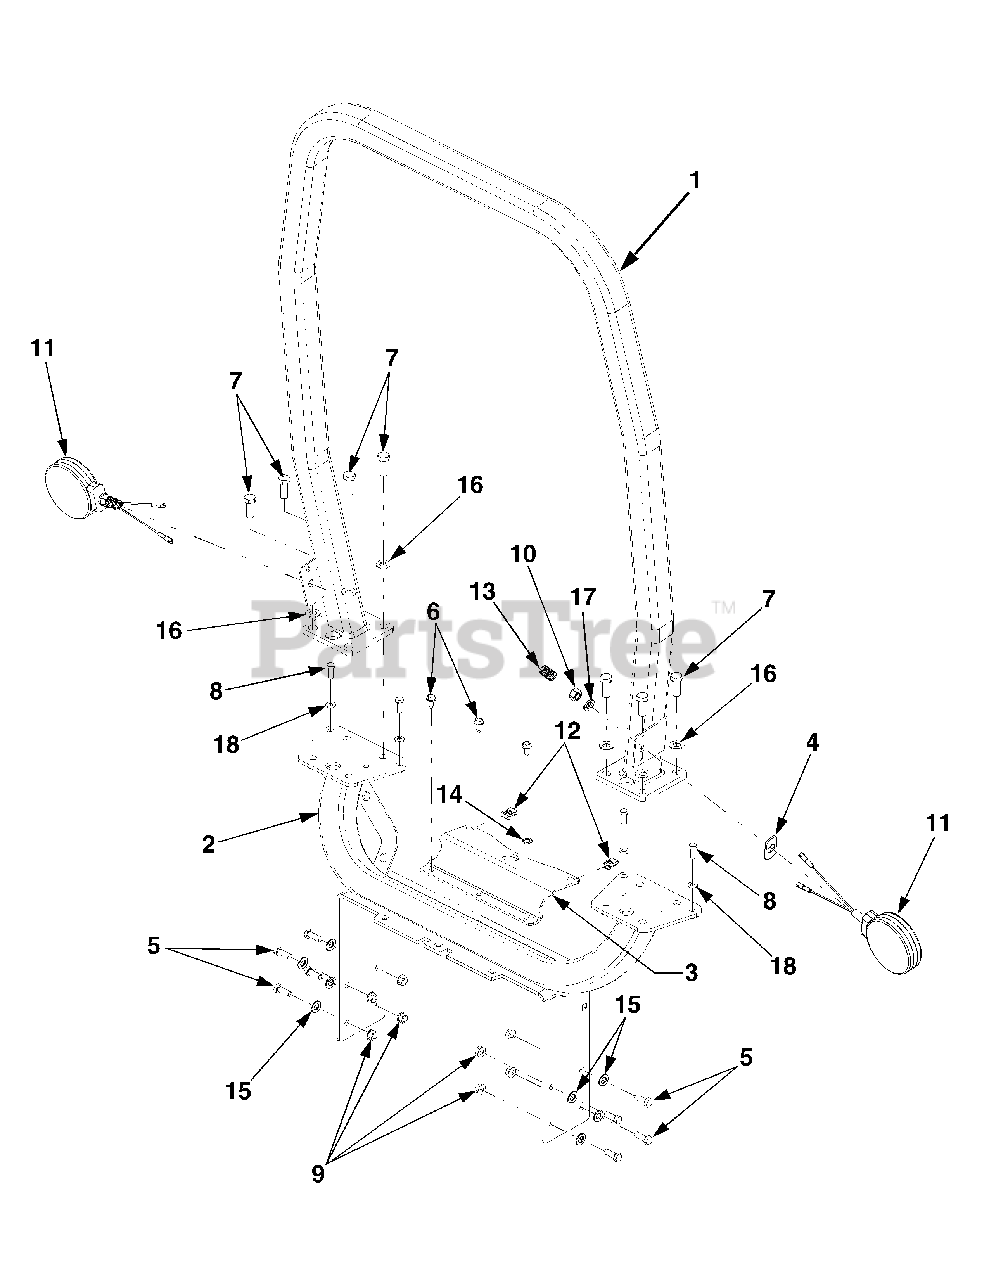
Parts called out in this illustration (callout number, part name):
1	Rops. Upper
2	Rops, Lower
3	Bracket, Rear Seat Mounting
4	Plate, Spacer
5	Screw, Hex Cap, 3/8-16 x 1.0 GR5
6	Screw, Hex Wash. Hd. Tapp 5/16-18 x .75
7	Screw, Hex Cap Lock, 1/2-13 x 1.25 GR5
8	Screw, Hex Cap, 5/16-18 x .875 GR5
9	Nut, Hex Insert Flange Lock, 3/8-16 GRF
10	Nut, Hex, 1/2-20 GR5
11	Light, Hazard
12	Nut, Speed, 5/16-18
13	Conduit
14	Washer, Ext. Tooth Lock, 3/8
15	Washer, Flat, .375 x .74x.063
16	Washer, Flat, .51 x 1.0 x .060
17	Washer, Lock, 1/2
18	Washer, Flat, .345 x 1.0 x .1
